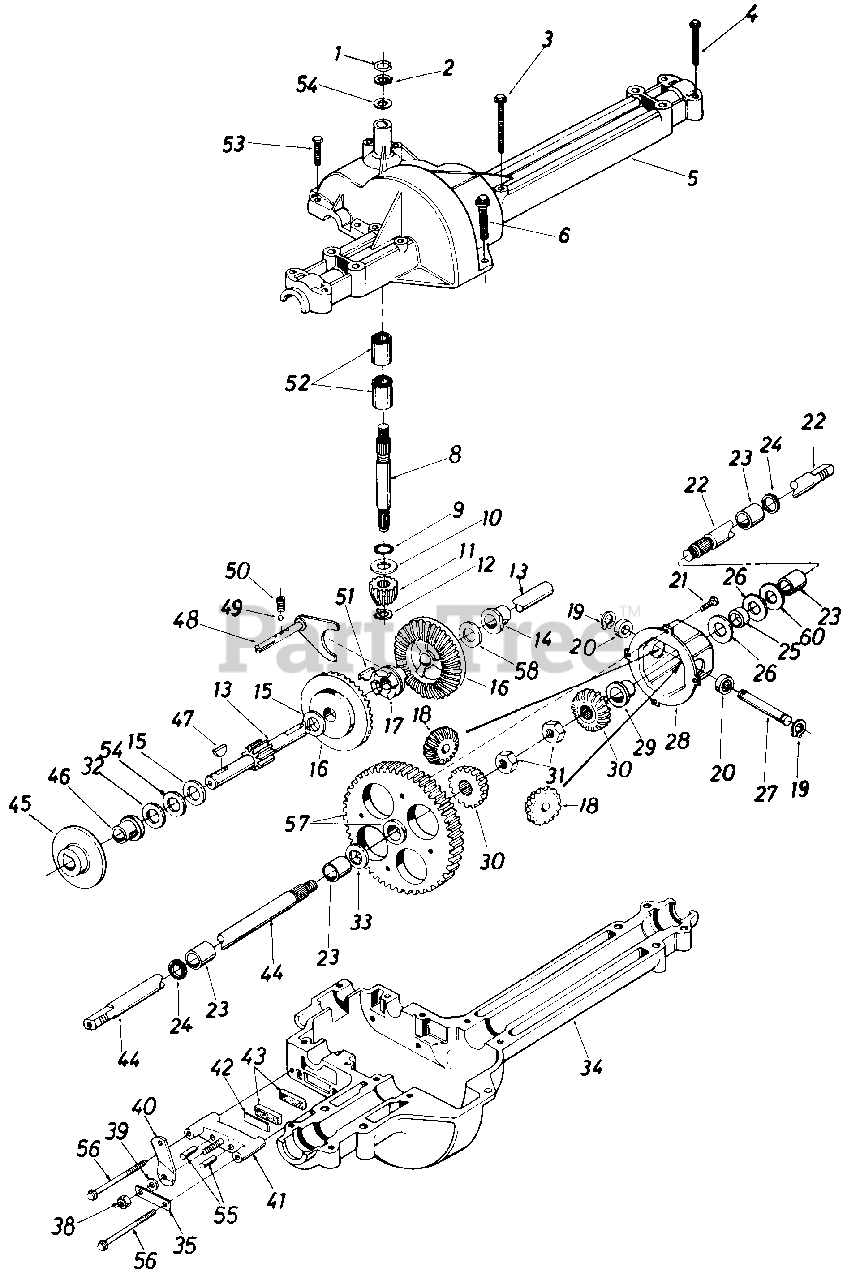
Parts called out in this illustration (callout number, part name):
2	Retaining-Ring
3	Hex Bolt 1/4-20 X 1.75" Lg.
4	Hex Tap Scr. 1/4-20 x 1.25" Lg.
5	Upper Housing
6	Hex TT-Tap Scr. 1/4-20 X .75" Lg.
9	Square Seal 518" I.D.
10	Thrust Washer 518" I.D. x 1.25" O.D.
11	Pinion Input 14T
12	Retaining Ring
14	Flange Brg. 5/8" I.D. x 3/4" Lg.*
15	Fl-Wash. 5/8" I.D. x 1.25"
16	Bevel Gear 42T
17	Clutch Collar
18	Miter Gear 15T
19	Snap Ring
20	Thrust Bearing
21	Pan Head Scr. 1/4-20 X .50" Lg. w/Patch
22	Axle R.H. Ass'y.
23	Sleeve Bearing 3/4" I.D. x 1.0" Lg.
24	Oil Seal 3/4" I.D.
26	Fl-Wash. .760" I.D. x 1.5" O.D.
28	Differential Cam Ass'y.
30	Miter Gear
31	Hex Jam Nut 1/2-20 Thd.
32	Thrust Wash. 5/8" I.D. x 1" O.D. x .025" Thk.
33	Fl-Wash. .760" I.D. x 1.5" O.D.
34	Lower Housing
35	Anti-Rotation Brkt.
38	Hex Nut 5/16-24 Thd.
39	Fl-Wash. .344" I.D. x .875" O.D.
40	Actuating Arm
41	Brake Yoke
42	Puck Plate
43	Brake Puck
44	Axle L.H. Ass'y.
46	Flange Bearing 518" I.D. x 15/16" Lg.
47	Woodruff Key 3/16 x 5/8 HT
48	Shift Fork Ass'y.
49	Ball Detent .250" Dia.
50	Spring Detent
51	#9 Hi-Pro Key 3116" x 3/4" Dia. HT
52	Needle Brg. 518" I.D. x '/2" Lg.
53	Hex Bolt 1/4-20 x 1.00" Lg.
54	Fl-Wash. 518" I.D. x 1" O.D. x .020 Thk.
55	Actuating Pin 5116" Dia.
56	Hex Wash Hd. Self-Tap Scr. 1/4-20 Thd.
57	Differential Gear 72T Ass'y. w/Bearing
58	Fl-Wash. 518" I.D. x 1" O.D. x .020 Thk.
60	Fl-Wash. .76" I.D. x 1.5" O.D. x .010" Thk.
